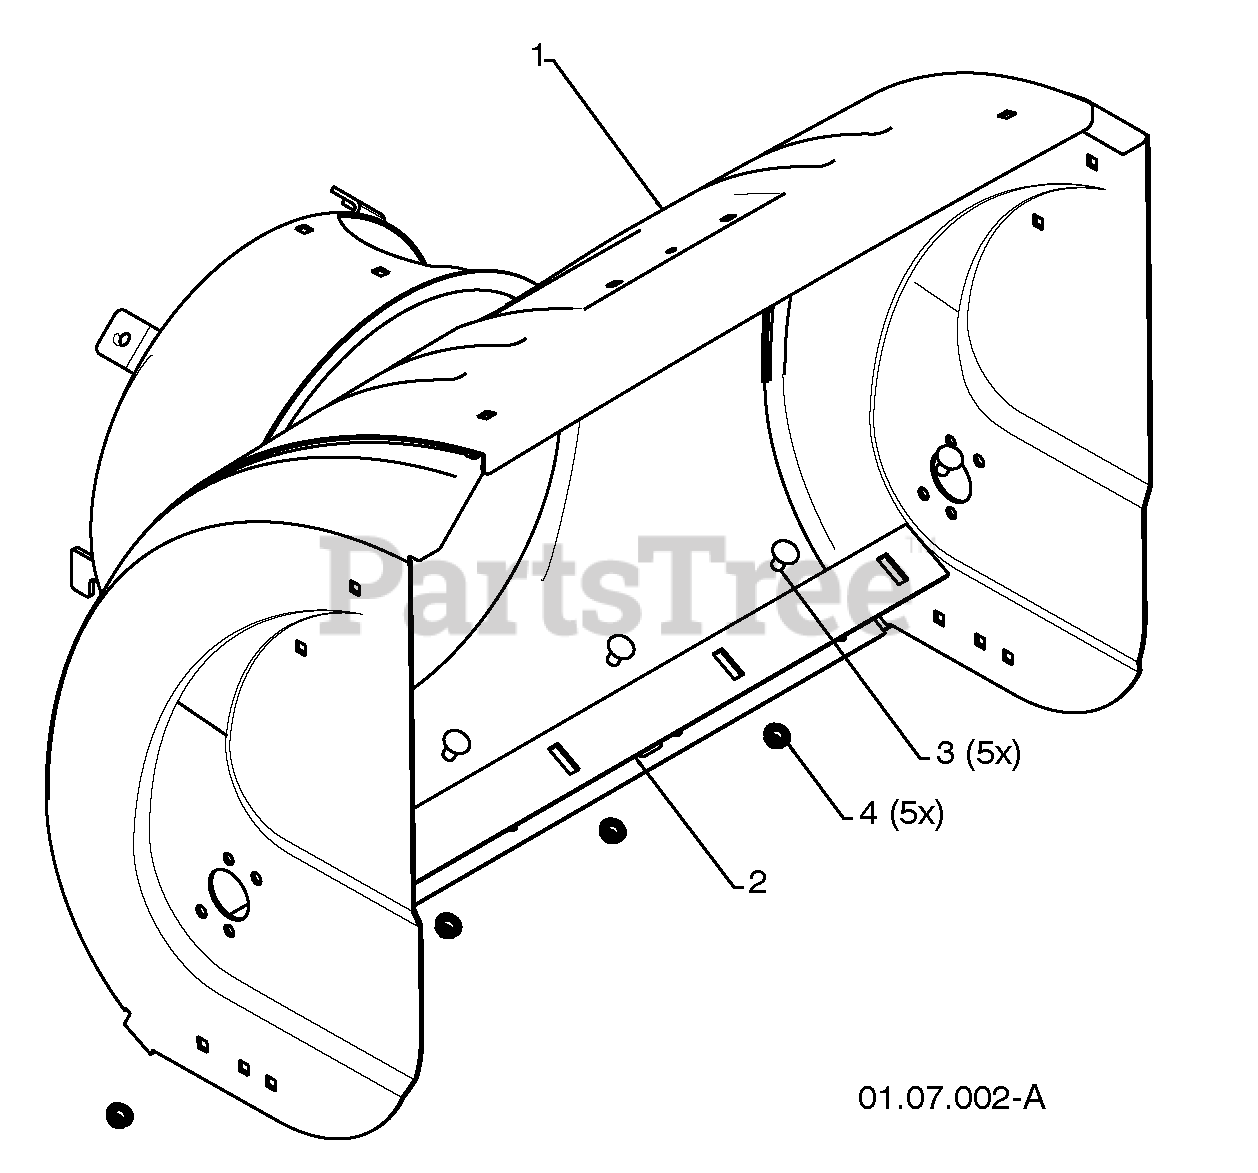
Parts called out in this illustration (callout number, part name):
1	AUGER HOUSING 27
2	SCRAPER BAR
3	CARRIAGE BOLT 5/16-18 X .625
4	NUT 5/16-18
